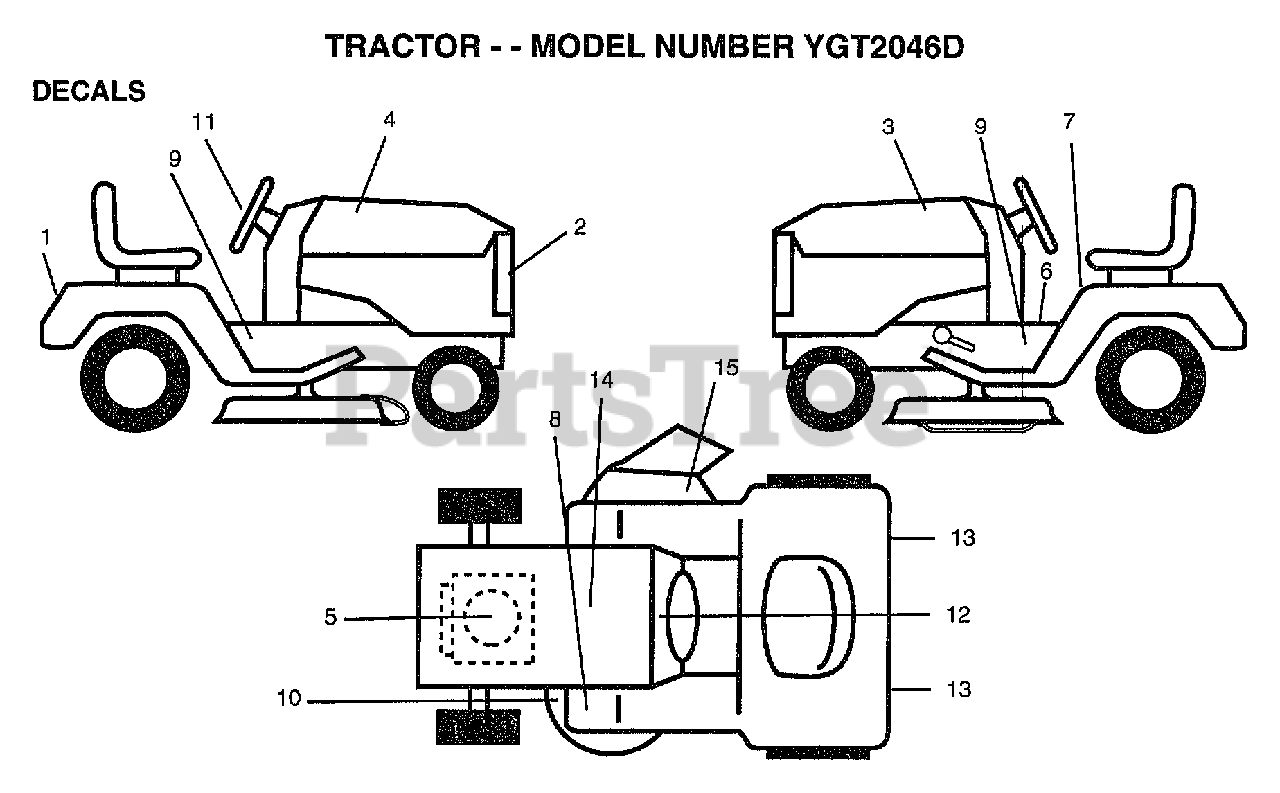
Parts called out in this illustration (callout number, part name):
1	DECAL FENDER
2	DECAL GRILLE
3	DECAL HOOD LH
4	DECAL HOOD RH
5	DECAL .B&S.20HP
6	DECAL BRAK PARK
7	DECAL.CAUT.ENG/FR
8	DECAL T
9	"DECAL CHASSIS,46"""
11	DECAL INS STRG WH
12	DECAL.INSTR.FRENC
13	REFLECTOR-TAIL YT
14	DECAL.BATRY.3-3908
15	"DECAL, WARNING"
